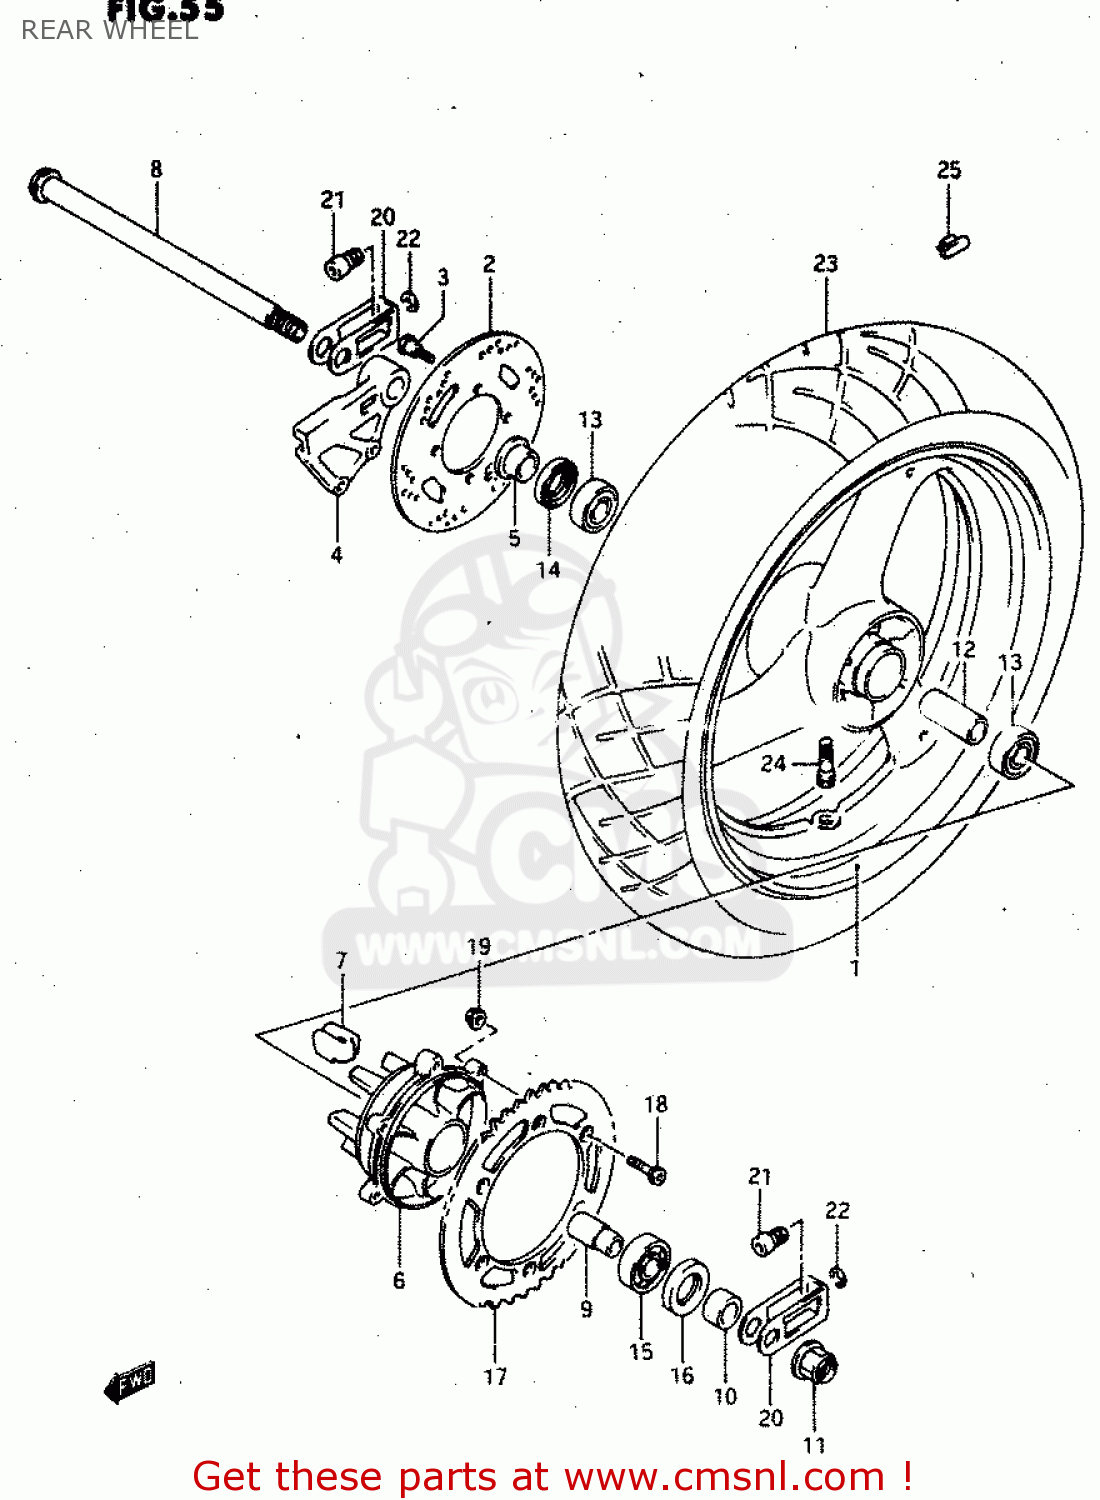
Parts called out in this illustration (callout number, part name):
1	WHEEL, REAR (17XMT4.50) GRAY
2	DISC,RR BRAKE
3	BOLT 8X33
4	BRACKET COMP,C
5	SPACER,RR AXLE,R
6	DRUM,RR SPROCKET MOUNTING
7	ABSORBER,RR HUB SHOCK
8	AXLE,RR
9	RETAINER,RR SPROCKET DRUM
10	SPACER,RR AXLE,L
11	NUT
12	SPACER,RR WHEEL BEARING
13	BEARING
14	SEAL,OIL(28X47X7)
15	BEARING
16	SEAL,OIL(34X54X8)
17	SPROCKET,RR(NT:43)
18	BOLT(8X30.5)
19	NUT
20	ADJUSTER,CHAIN
21	NUT,CHAIN ADJUSTER
22	CIRCLIP
23	TIRE, REAR (150/60 R17 66H) (BRIDGESTONE
24	VALVE ASSEMBLY,WHEEL,TR412
25	BALANCER,WHEEL
